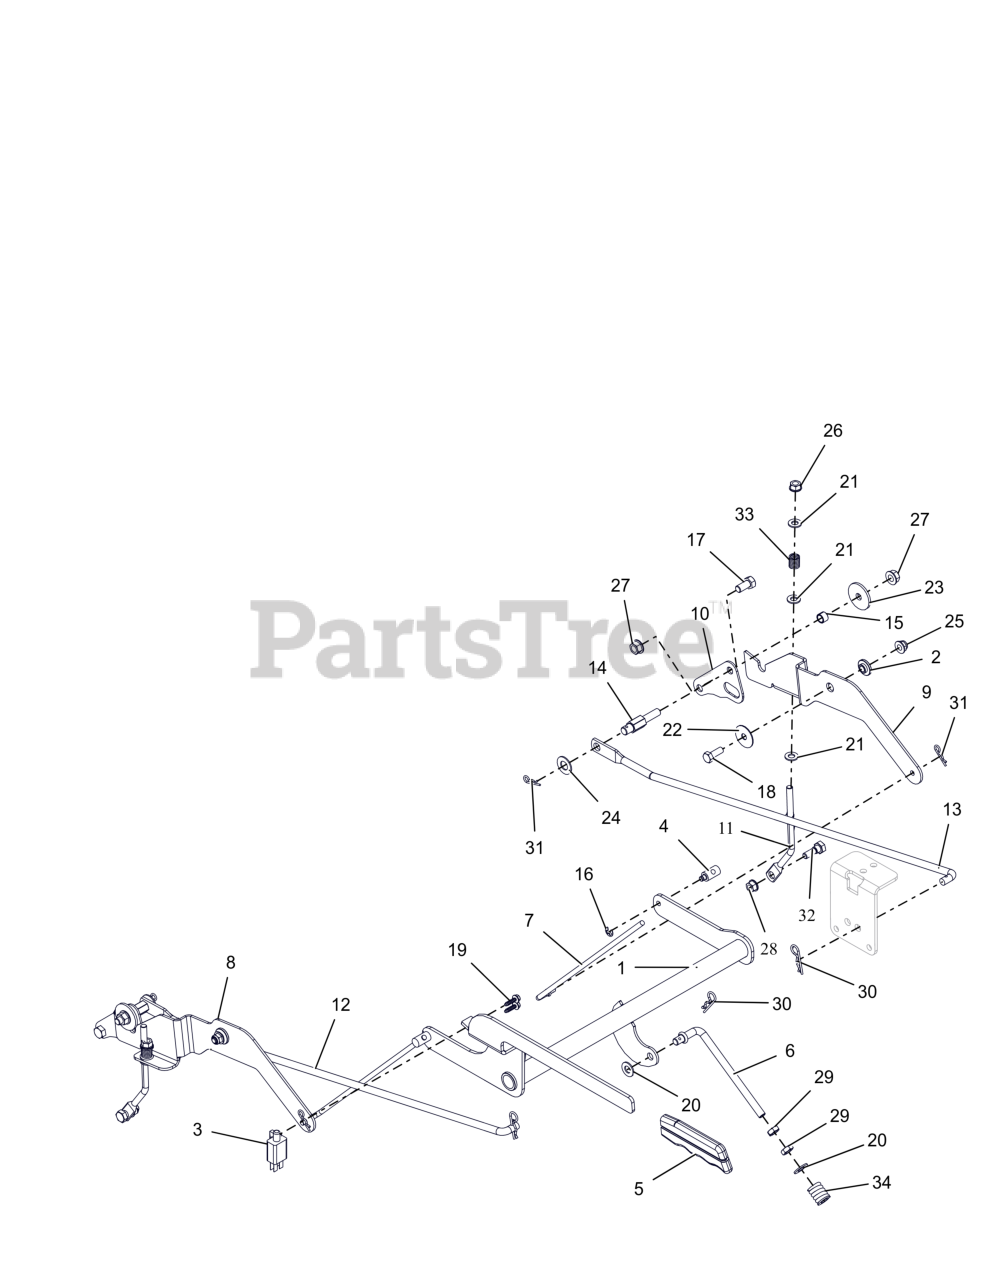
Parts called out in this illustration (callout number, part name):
1	WLDMT, BRAKE LEVER
2	BSHG, FLG .325X.499X.26X.88
3	SWITCH- DOUBLE POLE N.O./N.O.
4	TRUNION, 1/4-20
5	GRIP, PARKING BRAKE (YELLOW)
6	LINK, OVER CENTER, PARKING BRK
7	ROD, PARK BRAKE
8	INTERLOCK, RH BRAKE LINK
9	INTERLOCK, LH BRAKE LINK
10	PLATE, TRANSAXLE ADAPTOR
11	LINK, BRAKE (XL)
12	LINKAGE, STEERING - RH
13	ROD, STEERING LINKAGE LH
14	POST, STEERING LINK MOUNTING
15	SPCR, SLV .385X.500X.350
16	RG-RTNG-EXT .250X.025
17	BLT,HEX .38-16X.75 G5 ZCC
18	BLT, HEX .31-18X.875 G5 ZCC
19	SCR, PLASTITE-HWH 0.2 X 0.75 ZC120
20	WSHR,FLT .406X.812X.065 ZCC
21	WSHR,FLT .344X.688X.065 ZCC
22	WSHR, FLT .347X1.254X.048 ZCC
23	WSHR, FLT .380X1.50X.125 ZCC
24	WSHR, FLT .505X1.00X.062 ZCC
25	NUT,NYL-FLG .31-18 GF ZCC
26	NUT,LK-CTR-FLG .31-18 GF ZCC
27	NUT-LK-CTR-FLG .375-16 GF ZCC
28	NUT-LK-TOP-FLG .312-18 GF ZCC
29	NUT-JAM .375-16 G2 ZCC
30	PIN, HAIR .09 X 1.50 ZCC
31	PIN, HAIR #213 .08X1.19 ZCC
32	BOLT,SHLDR .38X.25 -.31-18X.75
33	SPRING, COMPRESSION
34	SG-COMP .187X.56X1.62
